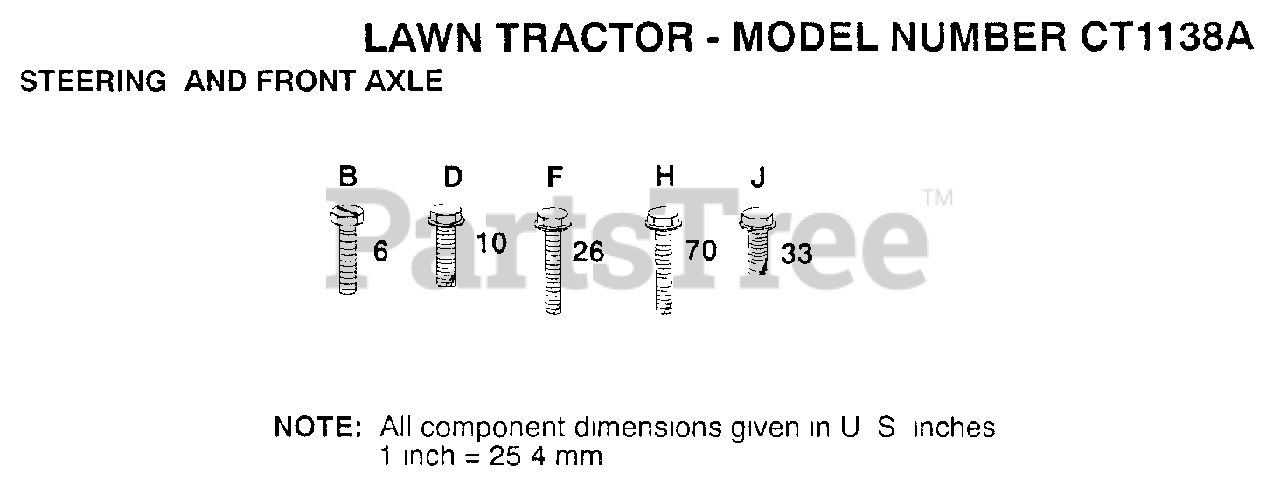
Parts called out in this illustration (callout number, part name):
6	SCREW LT
10	SCREW LT
26	SCREW
33	SCREW LT
